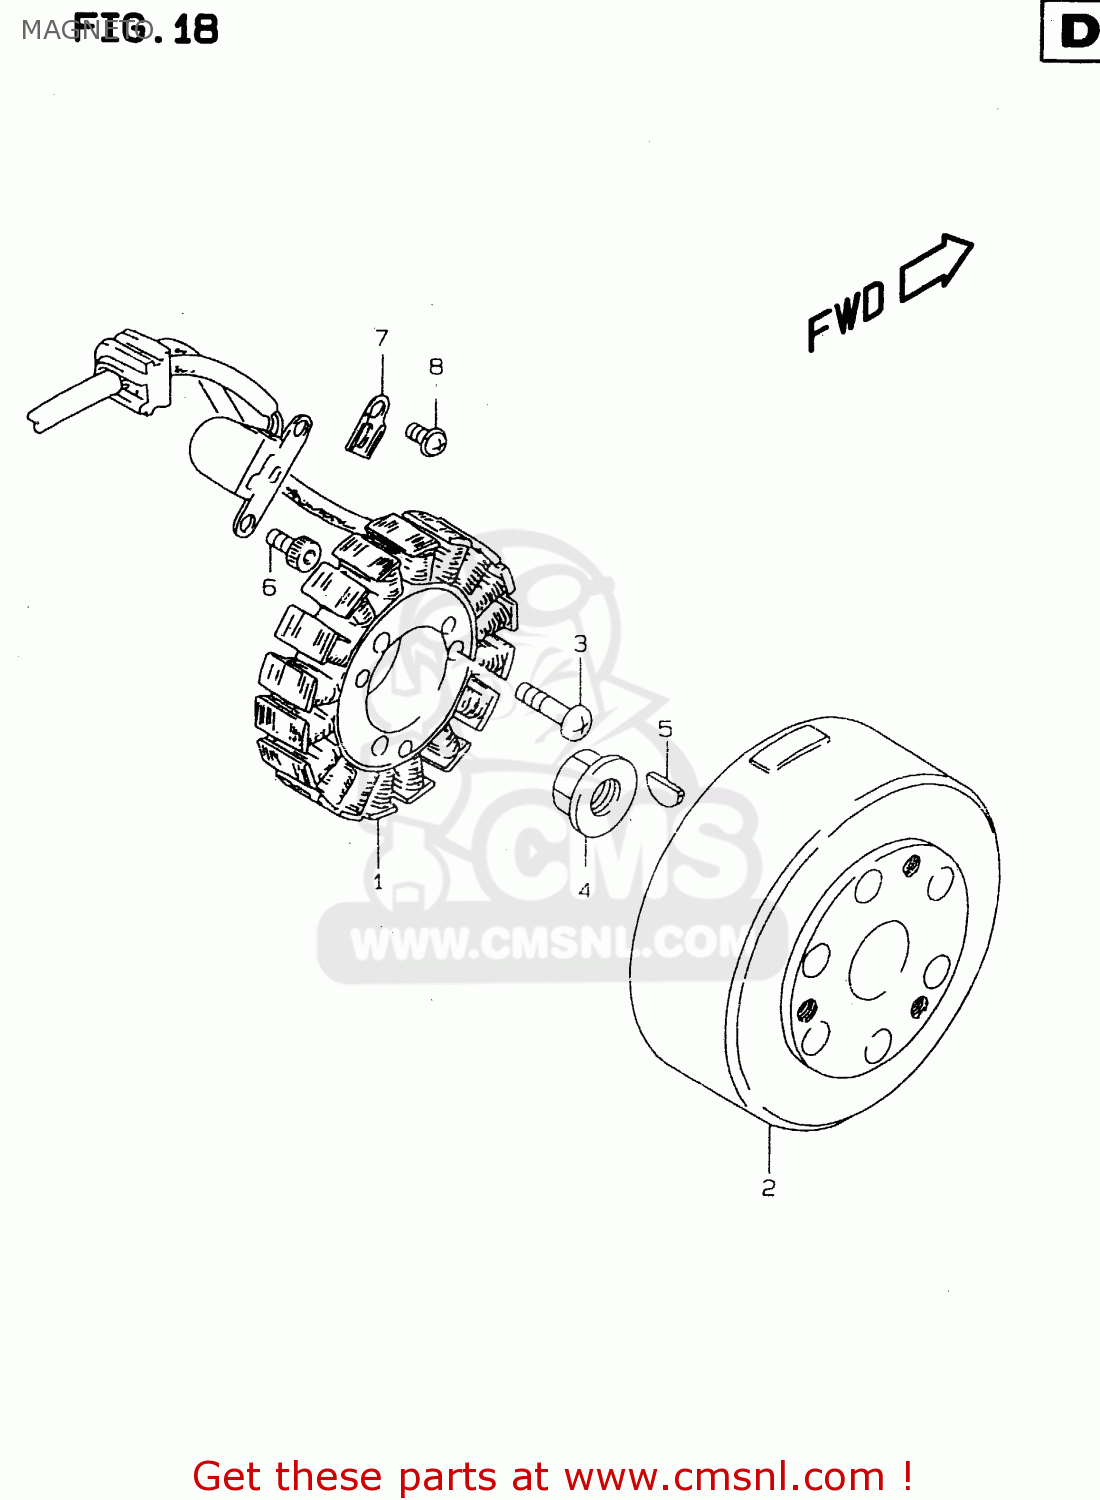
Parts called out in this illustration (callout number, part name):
1	STARTER ASSY
2	ROTOR ASSY
3	SCREW
4	NUT,GENERATOR ROTOR
5	KEY
6	BOLT
7	CLAMP,GENERATOR LEAD WIRE
8	SCREW
